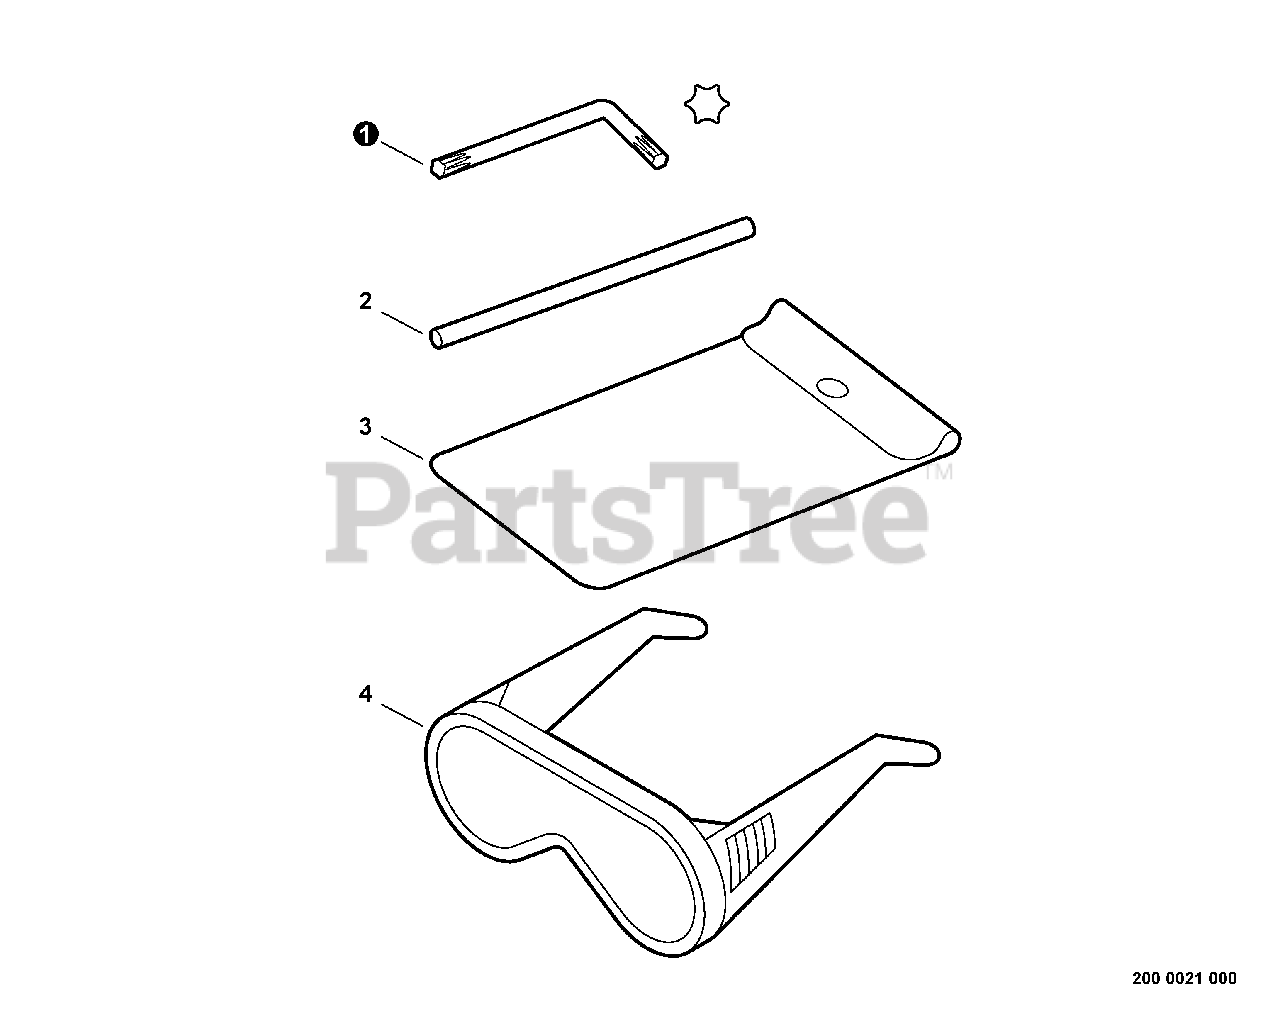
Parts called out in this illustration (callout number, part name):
1	KEY - TORX -- T27
2	ROD, LOCKING - 5X120mm
3	BAG, TOOL
4	GOGGLES
